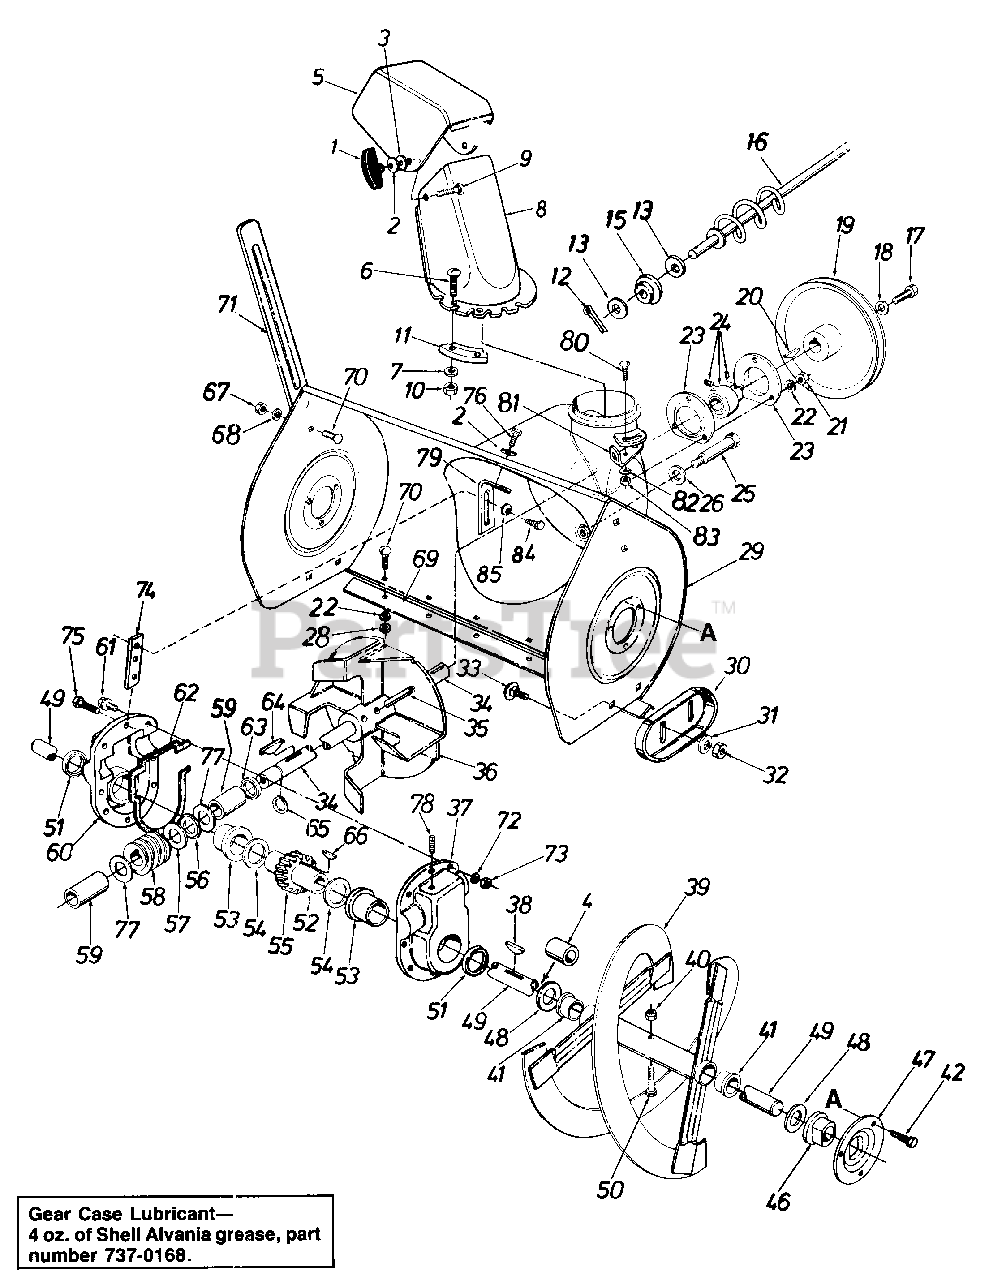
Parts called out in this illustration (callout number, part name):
1	KNOB-HANDLE ASSY
2	WASHER-BELL .337 x .867 x .057
3	WASHER-FL-.312 x 1.125 x .125
5	CHUTE-UPPER
6	SCREW-TRUSS MACH
7	WASHER-FL-.281 ID x .50 OD x .063
8	CHUTE-LOWER
9	BOLT-CARRIAGE 5/16-18 x 1.00
10	NUT-HEX CENTER L-1/4-20
11	KEEPER-CHUTE FLANGE
12	PIN-COTTER-3/32 DIA x .75
13	WASHER-FL-.385 ID x .62 OD x .063
15	BUSHING-.380 ID
16	CRANK ASSY-CHUTE
17	SCREW-HEX 5/16-18 x .88 SPECIAL
18	WASHER-BELL .337 x .867 x .057
19	PULLEY-V-1/2 ID x 10.0 OD
20	KEY-HI-PRO #9-3/16X3/4 DIA-HDN
21	NUT-HEX 5/16-18
22	WASHER-LOCK-5/16
23	HOUSING-BRG
24	BEARING-SELF ALIGN
25	STUD-3/8-16X2.75
26	WASHER-BELL .400 ID x .88 x .060
28	NUT-HEX 5/16-18
29	HOUSING ASSY-BLOWER
30	SLIDE SHOE
31	WASHER-BELL .400 ID x .88 x .060
32	NUT-HEX JAM 3/8-18
33	BOLT-CARRIAGE 3/8-16 x .62
34	AXLE-BLOWER
35	PIN-SPRING SPIR 5/16 x 1.75
38	KEY-WOODRUFF #91-1/4X3/4 DIA-HDN
42	SCREW-HEX HD TAP
46	BEARING-FLANGE
47	HOUSING-BRG
48	WASHER-FL
49	AXLE-SPRIAL
50	BOLT-HEX 5/16-18X1.75
51	SEAL-OIL
52	SHAFT-WORM GEAR
53	BEARING-FLANGE
54	WASHER-FL-1.50 x 2.25 x .030
55	GEAR-WORM-LH-DBL THD
56	BEARING-THRUST
57	WASHER-FL-881.D.X1.40 O.D.X.155
58	GEAR-WORM-LH-DBL THD
59	SLEEVE
60	HOUSING W/FL BRG-RH-GEAR
61	SCREW-HEX 5/16-18 x 1.00
62	GASKET-RUBBER
63	SEAL-OIL
64	KEY-HI-PRO #9-3/16X3/4 DIA-HDN
65	RING-SNAP FOR .875 SHAFT
66	KEY-WOODRUFF #91-1/4X3/4 DIA-HDN
67	NUT-HEX 5/16-18
68	WASHER-LOCK-5/16
70	BOLT-CARRIAGE 5/16-18 x .62
71	CUTTER-DRIFT
72	WASHER-SHAKE PROOF
73	NUT-HEX INS L-5/16-18
74	PLATE-SUPPORT-GEAR HSG
75	SCREW-HEX 5/16-18 x 1.25
76	SCREW-HEX HD TAP
77	WASHER-FL-881.D.X1.40 O.D.X.155
78	PLUG-VENTED-PLASTIC
80	BOLT-CARRIAGE 5/16-18 x .75
82	WASHER-BELL .337 x .867 x .057
83	NUT-HEX 5/16-18
84	SCREW-HEX 1/4-28 x .75
85	WASHER-SPRING BELL
